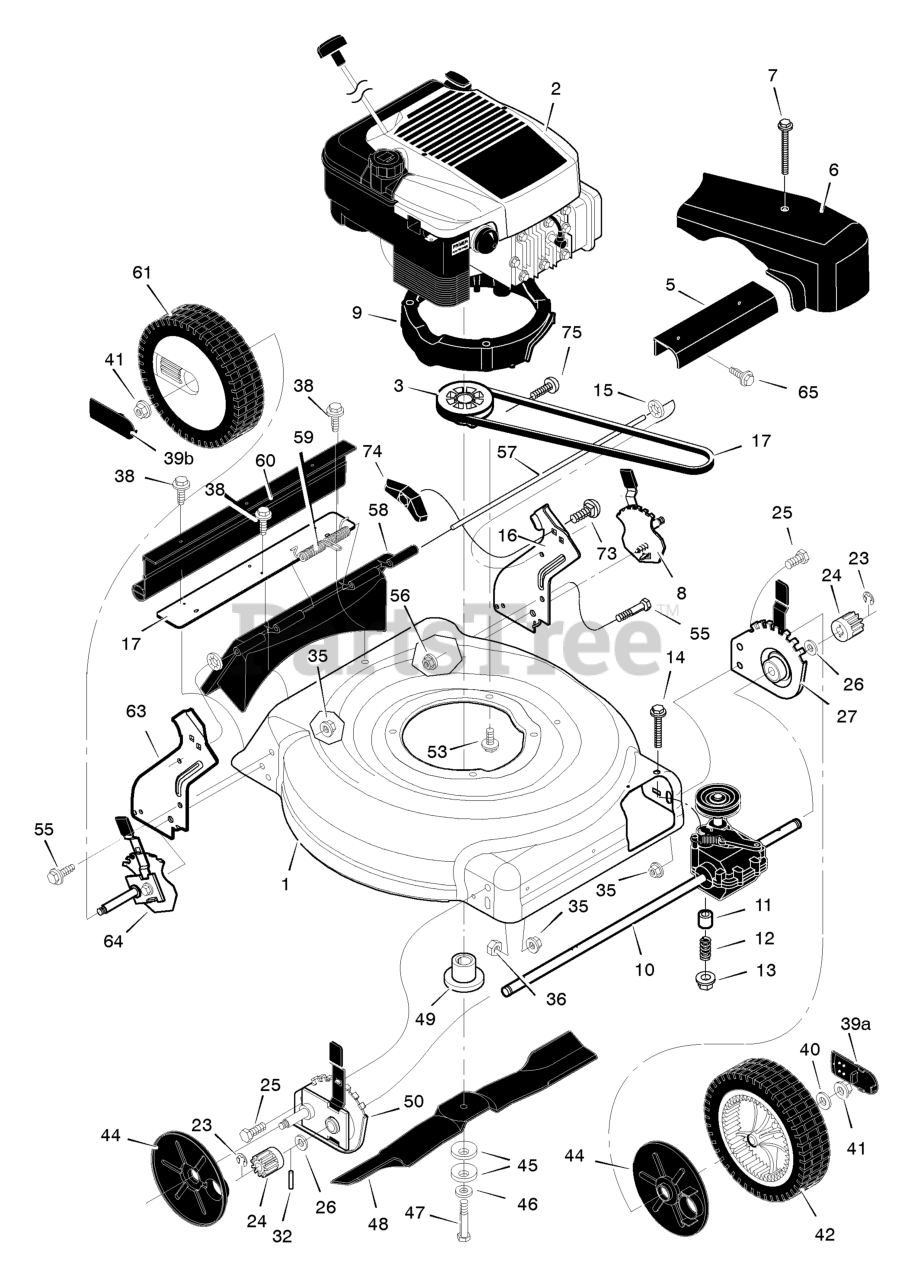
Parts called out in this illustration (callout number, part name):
2	Engine *
3	Pulley, Crankshaft
4	Pin, Spring
5	Cover, Axle (Gray)
6	Cover, Belt (Gray)
8	Adjuster, Left Height
9	Spacer, Engine
10	Transmission *
13	Nut
14	Bolt
15	Retainer, Push
16	Bracket, Left Handle
18	Extension, Rear
24	Gear, Pinion
25	Bolt
27	Adjuster, Left Frt. Height
32	Pin, Drive
35	Nut, Flange
39A	Cap, Hub
39B	Cap, Hub
40	Washer
41	Nut, Flange
42	Wheel, Drive
44	Cover, Dust
45	Washer, Belleville
49	Adapter, Blade
50	Adjuster, Right Frt. Height
53	Bolt, Engine
55	Bolt
56	Nut, Flange
57	Rod, Pivot
58	Door, Rear (Gray)
59	Spring
60	Deflector, Rear
61	Wheel, Rear
63	Bracket, Right Handle
64	Adjuster, Right Height
73	Bolt, Carriage
